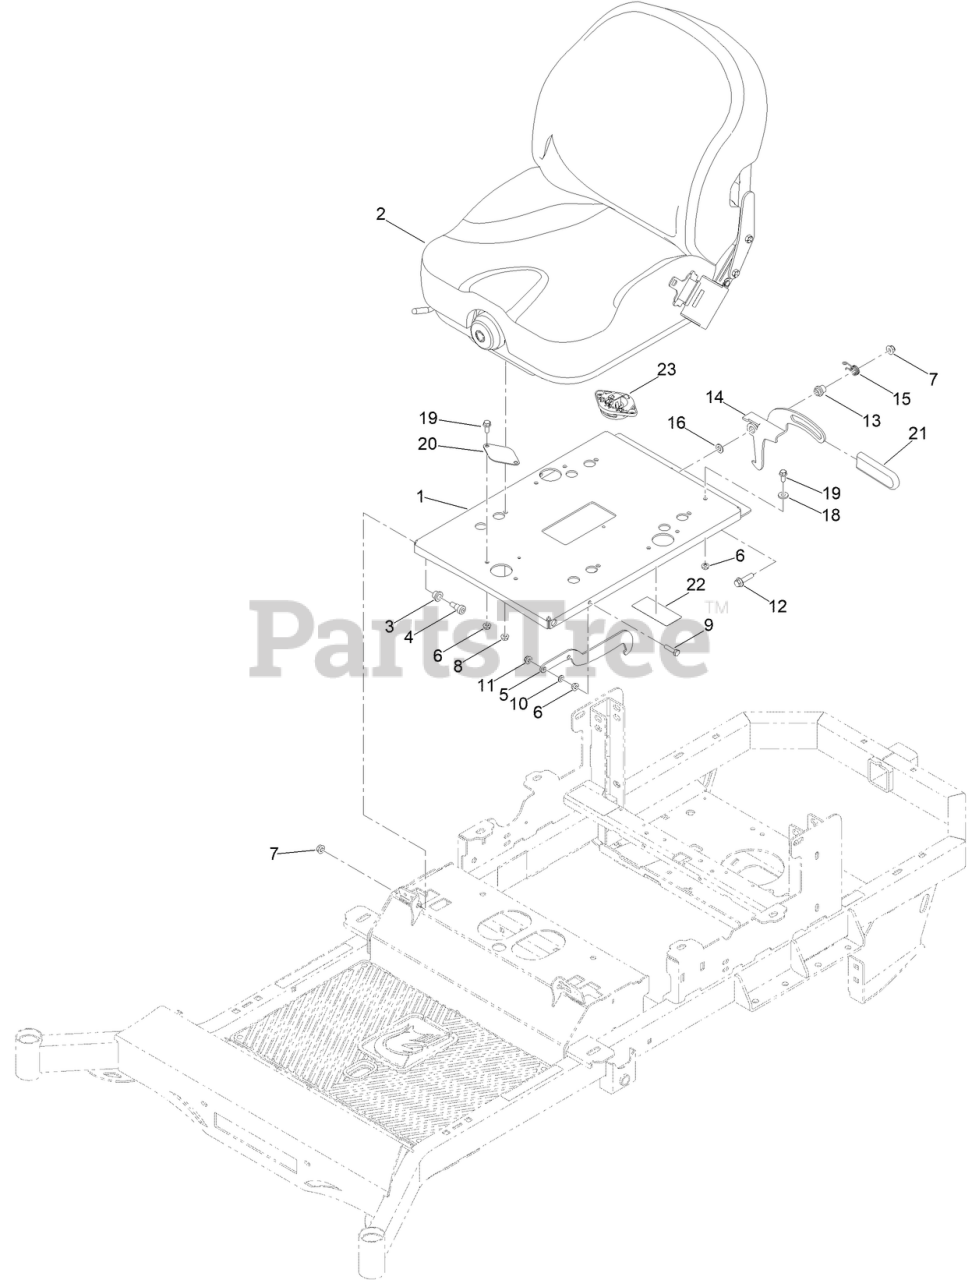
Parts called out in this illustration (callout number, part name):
1	NON 360 SEAT BASE PLATE SAFTY DECAL ASM-
2	2019 FULL SUSP SEAT
3	1/2IN ID X 5/8IN OD X 1/2IN FLANGE BUSH
4	1/2 X 1/2 SOCKET SHOULDER BOLT ZC YELLOW
5	MWR SEAT LATCH HOOK PAINT
8	5/16-18 NYLON INSERT FLANGE L/NUT ZC
9	SCREW-HH
10	.312IDX.625ODX.062 THK THRUST BRG OI BRZ
11	NUT-HF, NI
12	SCREW-HHF
13	BUSHING-LATCH, SEAT
14	BRACKET-LATCH
15	SPRING-TORSION, LATCH
16	WASHER-FLAT
18	.312 ID X .875OD X .1875 THK F/W NYL
19	SCREW-HHF
20	2020 RT/SRT UNIV FLOAT SEAT CVR PLT
21	STAND UP MWR BRAKE ARM GRIP
22	DECAL-WARNING, BATTERY
23	MWR SEAT SWITCH
